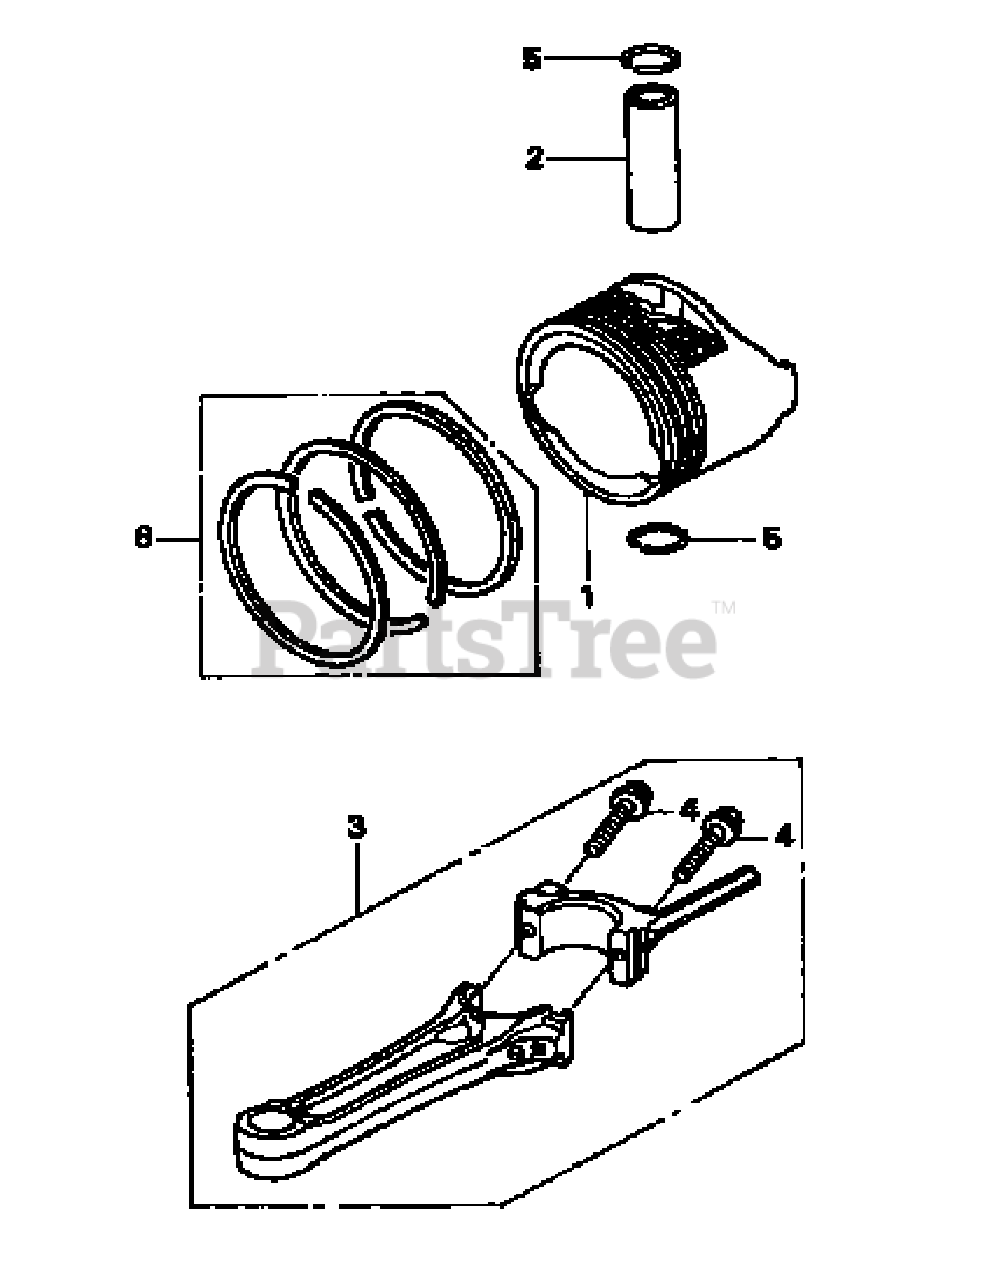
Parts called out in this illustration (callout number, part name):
2	Piston Pin
3	Connecting Rod Assy.
4	Connecting Rod Bolt
5	Piston Pin Clip (13mm)
6	Piston Ring Set
